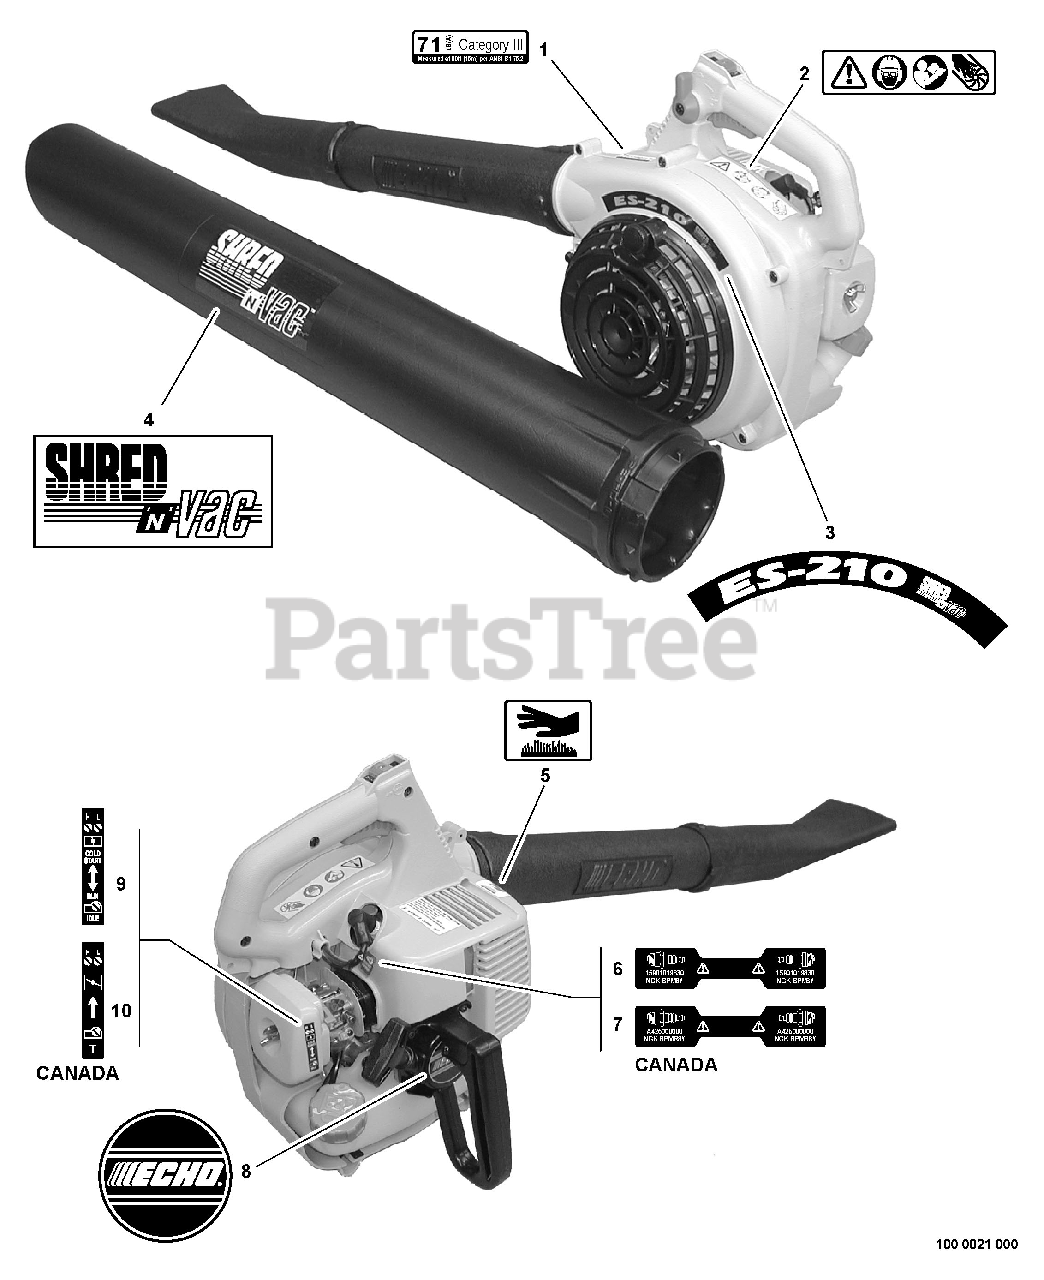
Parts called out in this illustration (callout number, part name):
1	LABEL - NOISE 71dB(A) CAT III
2	LABEL - CAUTION
3	LABEL - MODEL ES-210
4	LABEL - SHRED 'N' VAC
5	LABEL - HOT SURFACE
6	LABEL - SPARK PLUG -- BPM-8Y
7	LABEL - SPARK PLUG -- BPMR-8Y
8	LABEL - ECHO
9	LABEL - CHOKE
10	LABEL - CHOKE
